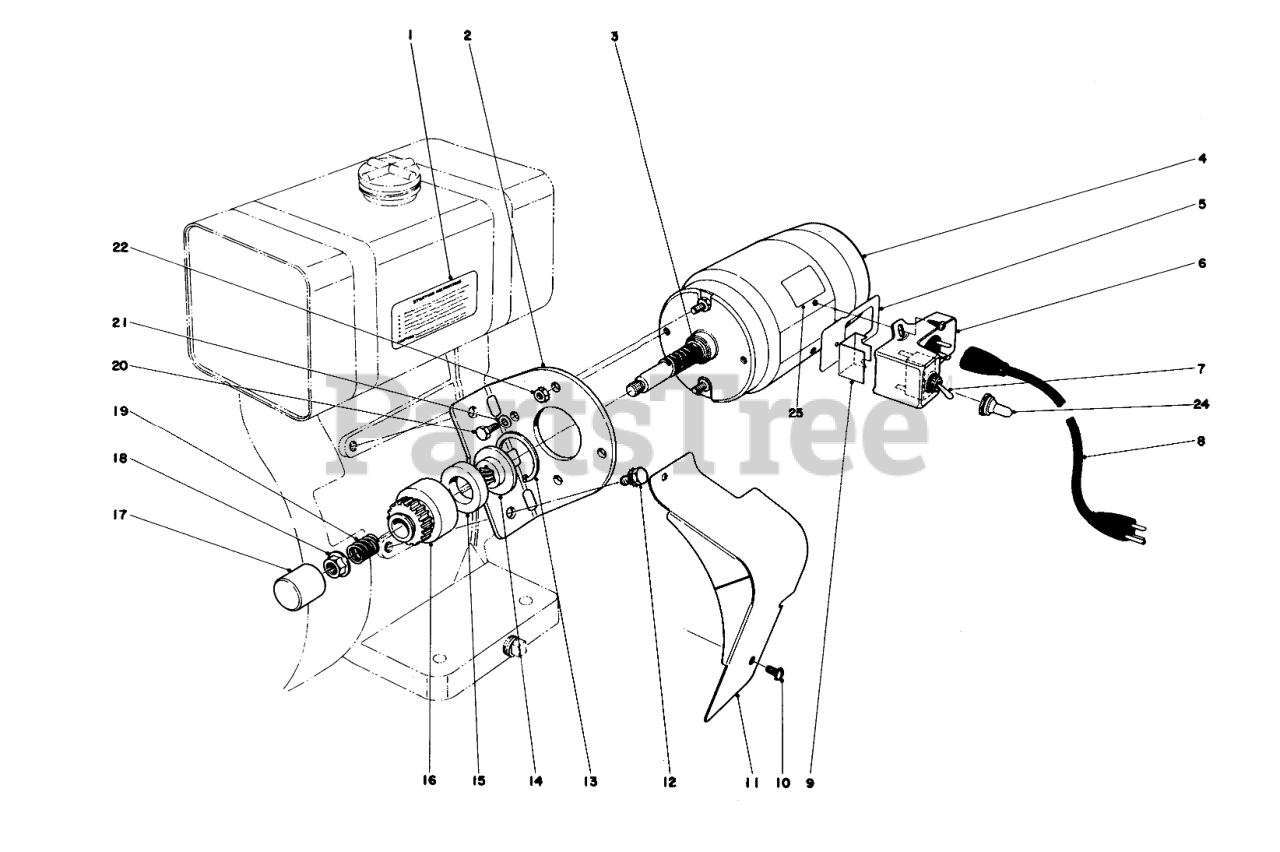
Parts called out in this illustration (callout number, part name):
1	Instruction Decal
2	Mounting Bracket
3	Spacer
4	Starter Motor, U.S.A.
5	GASKET
6	Switch & Plug Housing
7	SWITCH & BOOT ASM
9	SWITCH INSULATOR
10	Hex Hd. Sems Screw
11	Pinion Shield
12	5/16-18 X 5/8 SEMS SC
13	Retaining Clip
14	Pinion Nut
15	Rubber Ring
16	PINION 16 TOOTH
17	WEATHER CAP
18	NUT-HHF
19	COMPRESSION SPRING
20	SLOT HD SCREW
21	WASHER-LOCK, INT
22	NUT-KEPS
24	Boot-Switch
25	Decal
